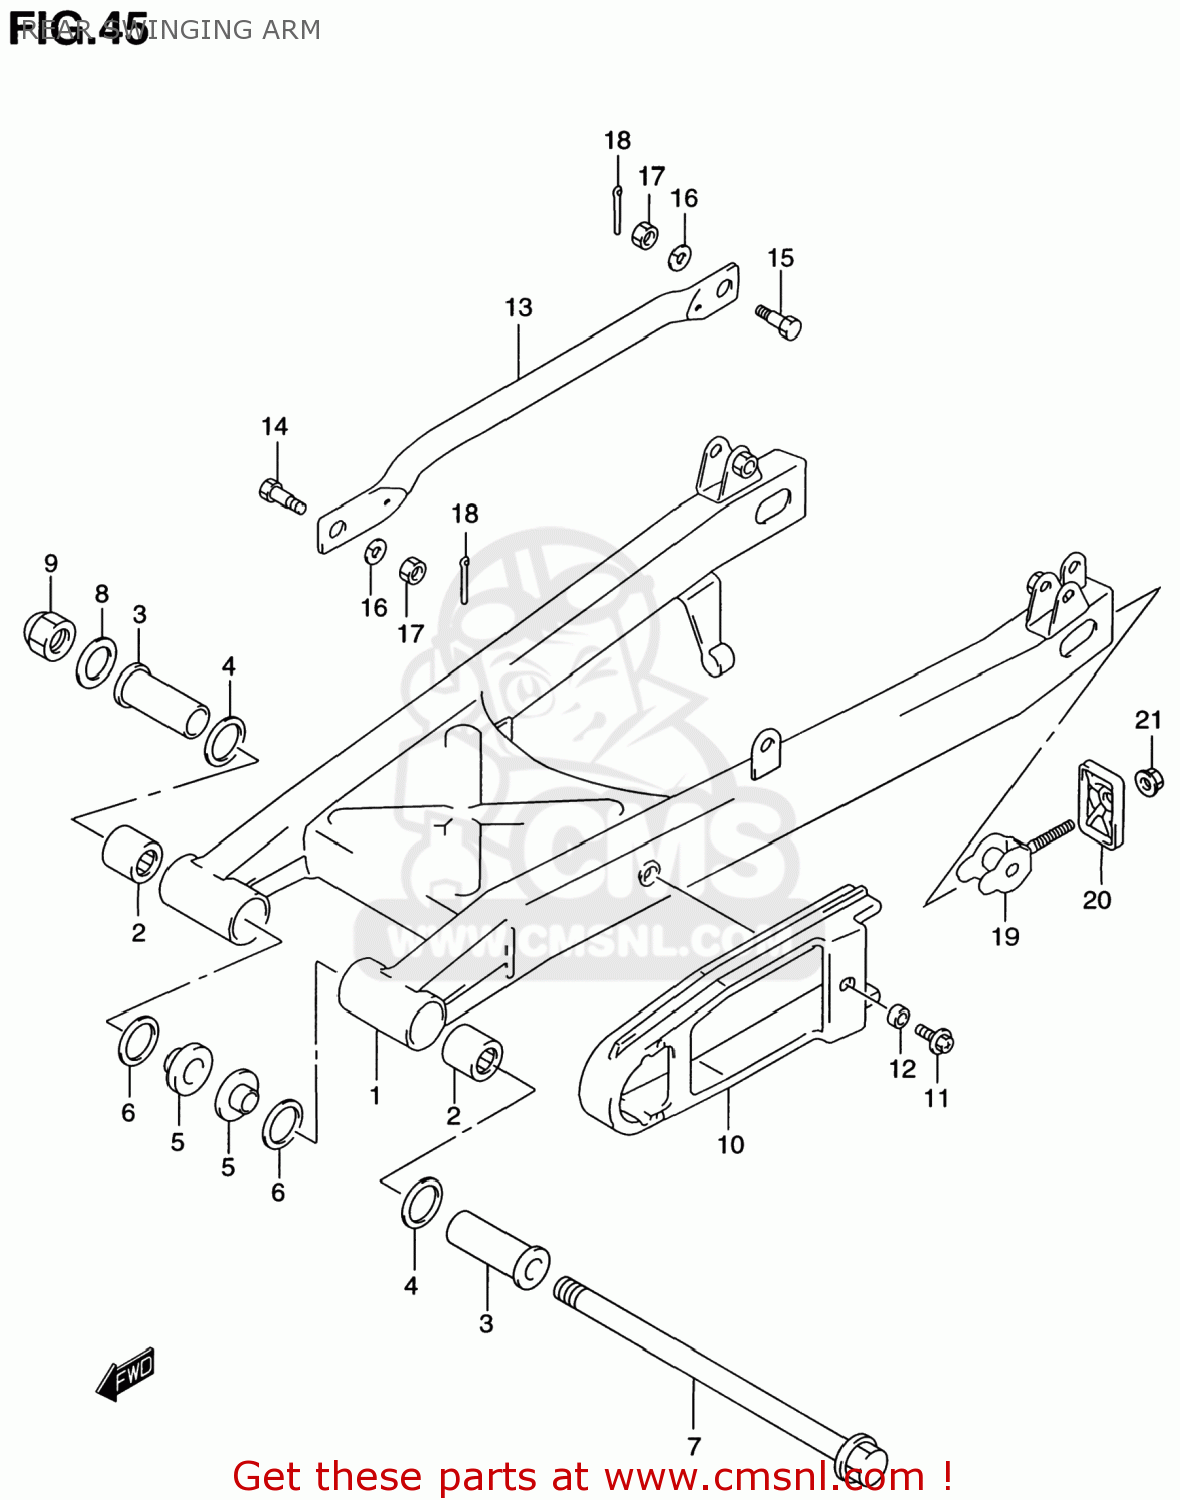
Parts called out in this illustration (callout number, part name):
1	SWINGINGARM ASSY,RR
2	BEARING(20X27X20)
3	SPACER,RR SWGARM PIVOT OUTER
4	SEAL,OIL(20X27X5)
5	SPACER,RR SWGARM PIVOT INNER
6	SEAL,OIL(20X27X5)
7	SHAFT,RR SWINGINGARM PIVOT
8	WASHER
9	NUT 14MM
10	BUFFER,CHAIN TOUCH DEFENSE
11	BOLT(6X20)
12	SPACER(6.5X9X3.8)
13	TORQUELINK,RR
14	BOLT(8X22.5)
15	BOLT(8X26.5)
16	WASHER,LOCK
17	NUT
18	PIN 20X20
19	ADJUSTER,CHAIN
20	PLATE,CHAIN ADJUSTER
21	NUT
